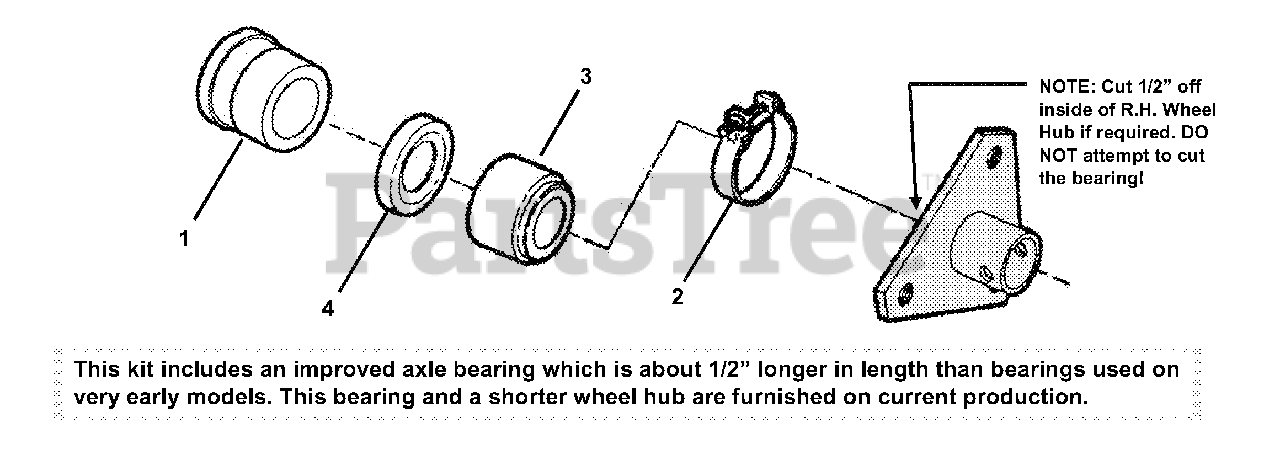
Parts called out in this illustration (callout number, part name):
1	BEARING, Axle
2	CLAMP, Boot
3	CAP, Seal
4	SEAL, Oil
